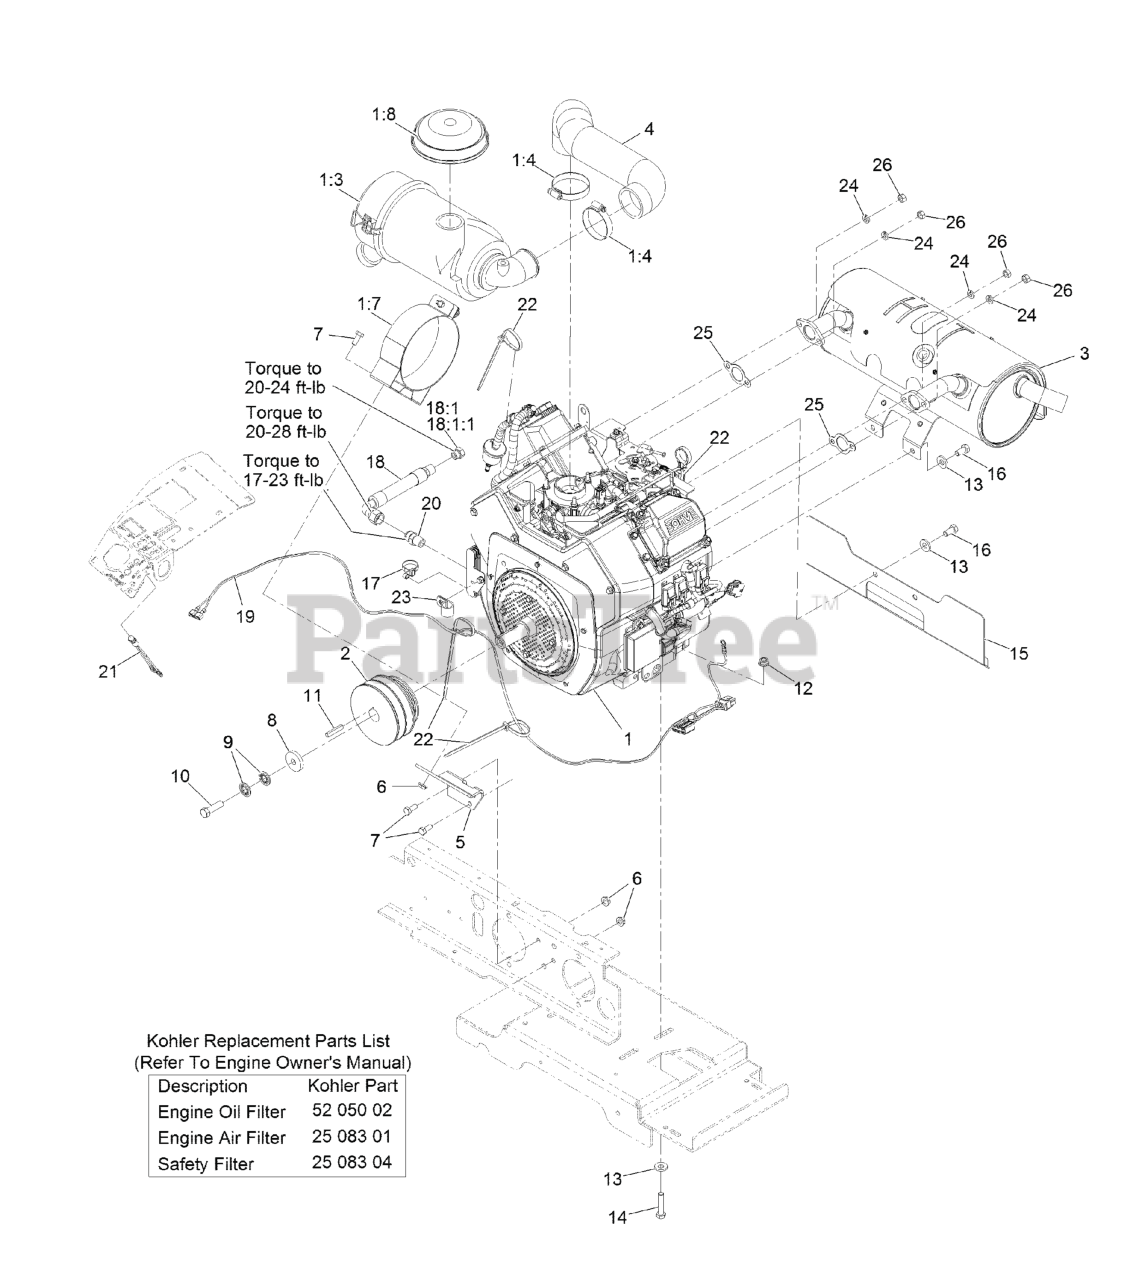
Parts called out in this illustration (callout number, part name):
1:3	AIR CLEANER CANISTER ASM
1:4	CLAMP-HOSE
1:7	BRACKET-FILTER, AIR
1:8	HOOD-CLEANER, 2" AIR INTA
3	MUFFLER
4	HOSE-EFI AIR INTAKE
5	BRACKET-FILTER, AIR
7	SCREW-HH
8	WASHER-CLUTCH
9	WASHER-SPRING
10	SCREW-HH
11	KEY-SQUARE
12	NUT-HHF, WHIZ
13	WASHER-BELLEVILLE
14	SCREW-HH
15	SHIELD-EXHAUST
16	SCREW-HH
17	Tie, Cable
18	OIL DRAIN HOSE ASM
18:1	PLUG-HH
18:1:1	O-RING
19	HARNESS-LIGHT INDICATOR (
20	FITTING-STRAIGHT
21	INDICATOR-LED, RED
22	TIE-PLASTIC
23	CLIP-LOOM
24	WASHER-LOCK
26	NUT-HEX
